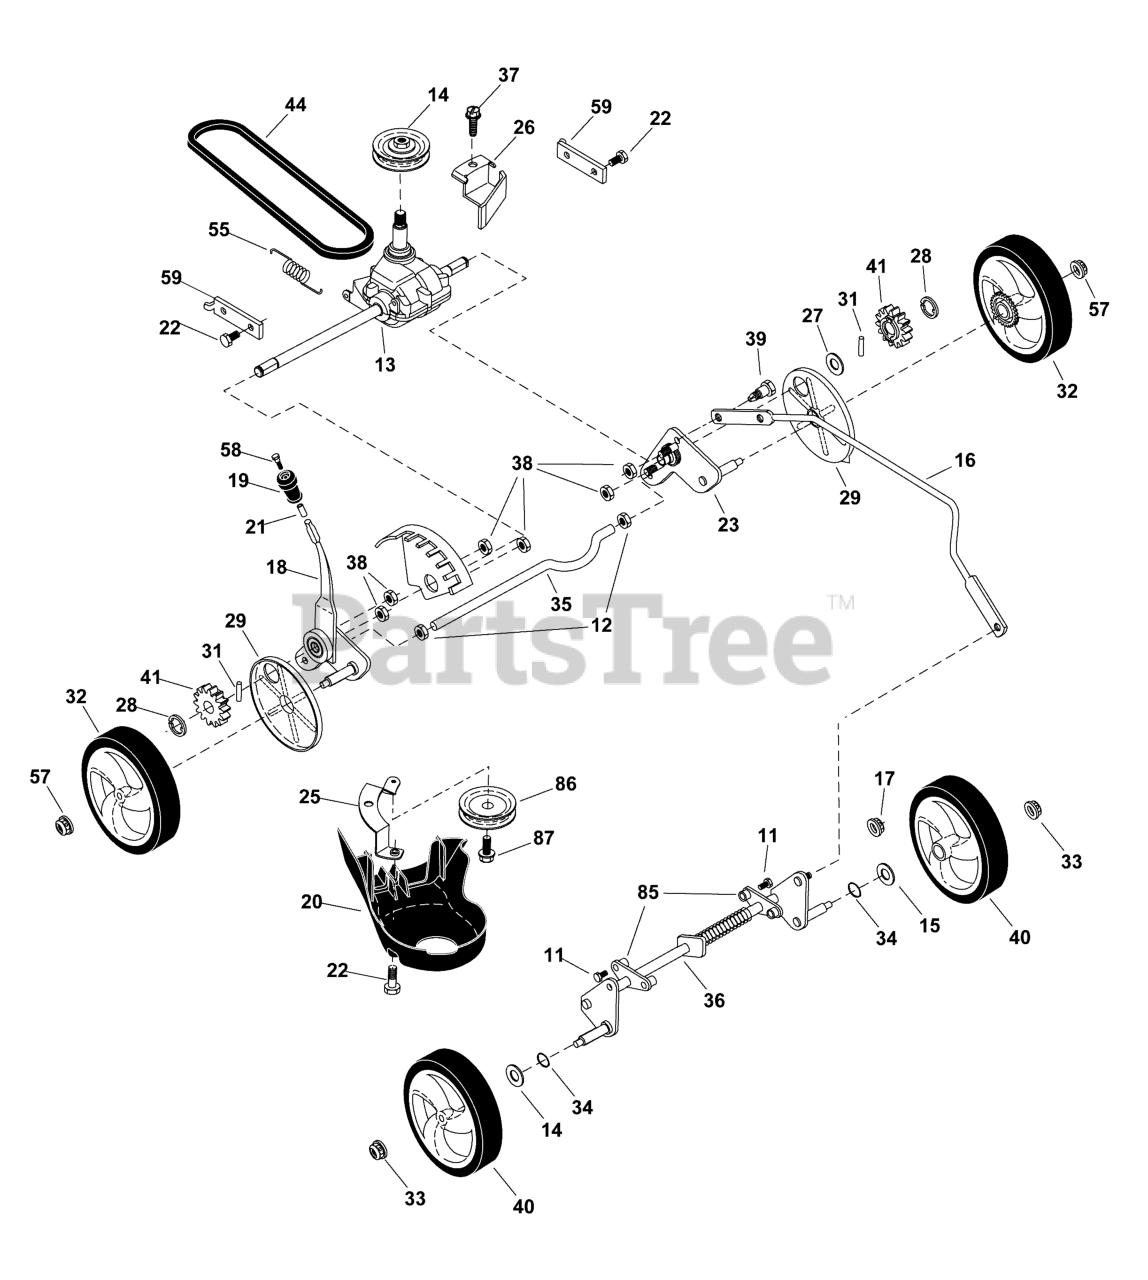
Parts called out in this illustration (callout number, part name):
11	Screw, Hex Washer Head, #13 x 3/4
12	Nut Hex Jam Toplock 1/2-20 unf
13	GEARCASE ASSEMBLY, Rear
15	WASHER, Flat, 3/8
16	ROD, Height Adjust
17	Locknut, Hex 5/16-18
18	LEVER, Height Adjust
20	COVER, Debris
21	INSERT, Threaded
22	SCREW, FRONT BAFFLE
23	AXLE, Rear
25	BRACKET, Mounting
26	GUIDE, Belt
27	WASHER, Flat
29	COVER, Wheel, Dust
31	Pawl, Drive
32	WHEEL ASSEMBLY, Rear
33	NUT, LOCK FLG, 3/8-16
35	AXLE, Rear
36	AXLE, Front
37	SCREW, Hi-Lo Thread, #12 x 5/8
38	Nut, Hex, Flanged 1/4-20
39	CAPSCREW
40	WHEEL ASSEMBLY, Front
41	GEAR, Drive
44	BELT, Drive
55	SPRING, Tension
57	NUT, Lock Flange, 3/8-16 UNC
59	BRACKET, Support
85	BRACKET, support
86	PULLEY, Idler
